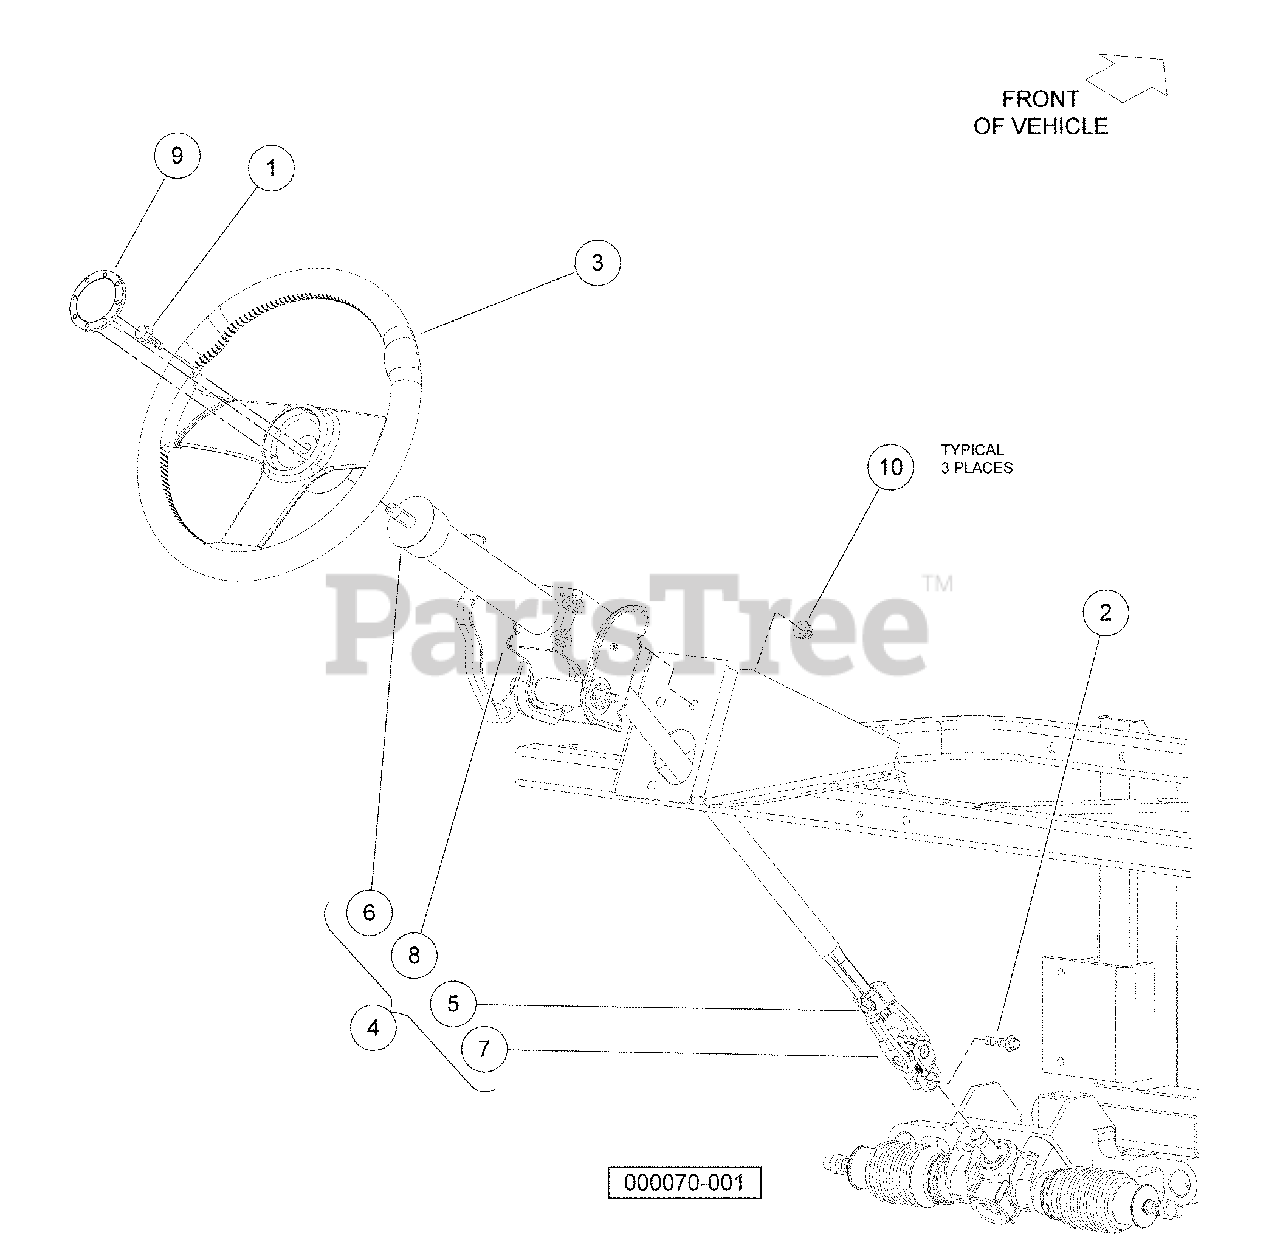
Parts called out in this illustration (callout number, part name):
1	Bolt, M10 X 20 Hex Washer Hd
2	Bolt, Flange Head, M8 X 30.0
3	Steering Wheel, Viper, Hex Hub
4	Steering Column
5	Bolt, Flange Head, M8 X 30.0
6	Shroud, Steering Column
7	Knuckle, Steering, Slider
8	Column, Steering without Knuckle and Shroud
9	Cap, Steering Wheel, Viper
10	Lock Nut, Flg M8 X 1.25 Nylon
